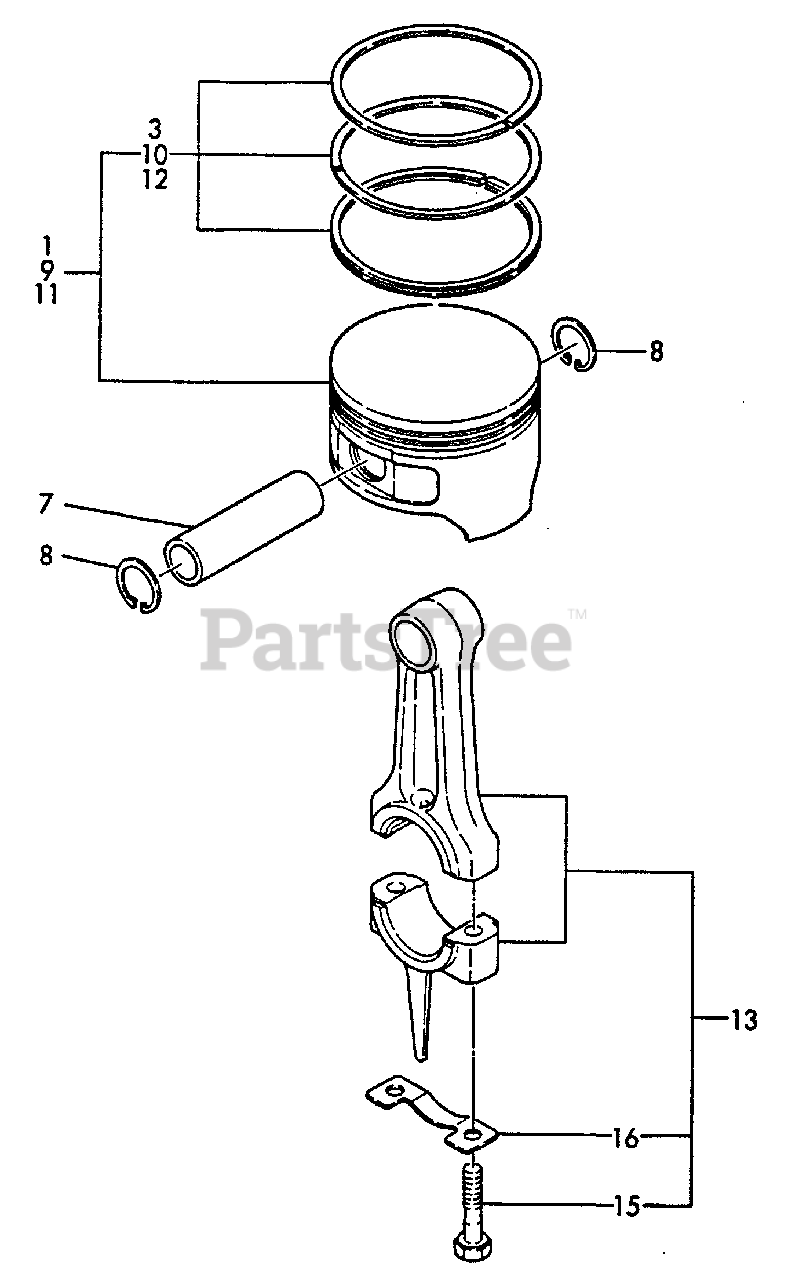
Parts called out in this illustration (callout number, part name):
1	PISTON ASSY
3	PISTON RING ASSY
7	PIN, PISTON
8	RING, RETAINING - 19
9	PISTON ASSY O.S.= 0.25
10	RING ASSY O.S.= 0.25
11	PISTON ASSY O.S.= 0.5
12	RING ASSY O.S.= 0.5
13	CONNECTING ROD ASSY
15	BOLT, ROD
16	WASHER, BOLT
